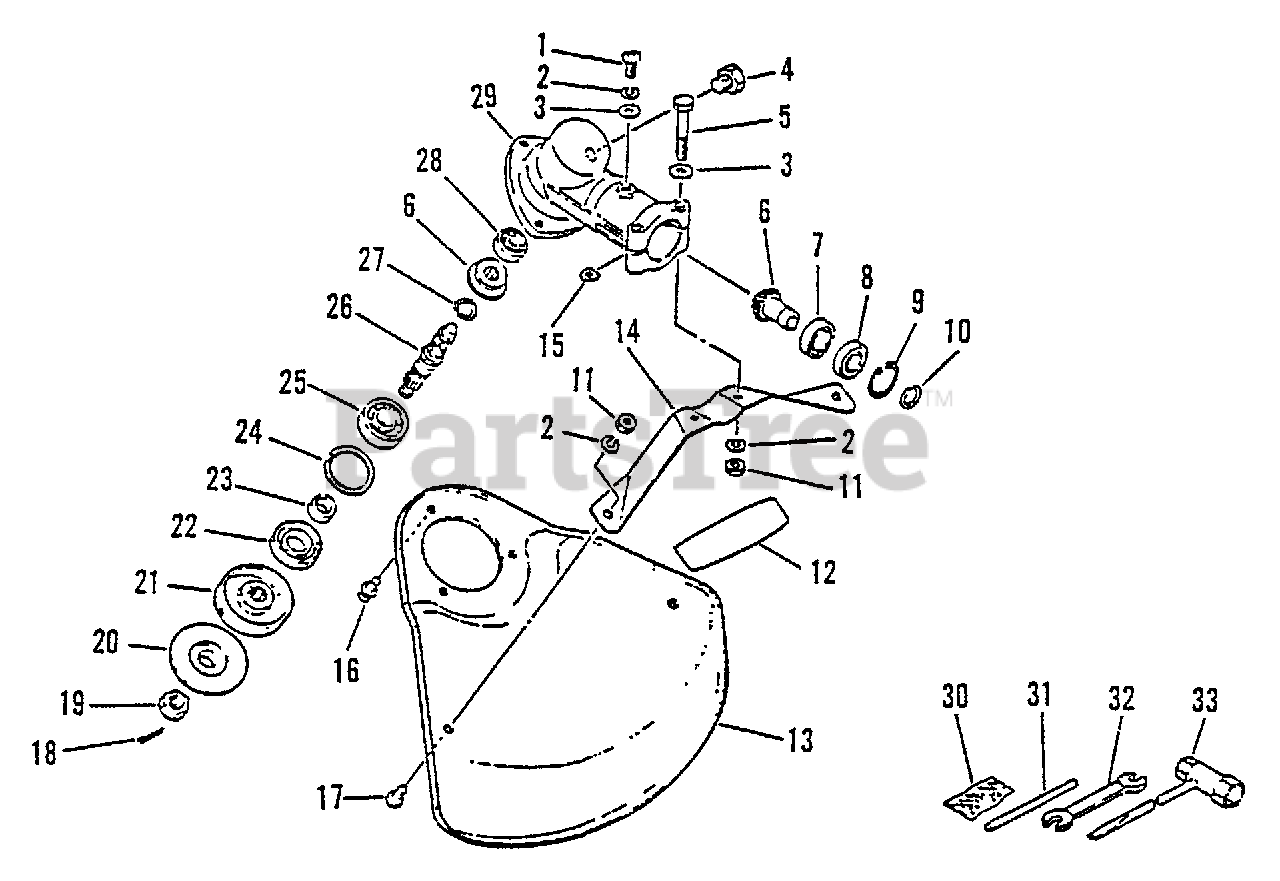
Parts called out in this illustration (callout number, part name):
1	SCREW - 5X10
2	LOCKWASHER - 5
3	WASHER - 5
4	BOLT - 8X8
5	BOLT - 5X35
6	GEAR SET - BEVEL
7	BEARING, BALL - 6900
8	BEARING, BALL - 6900Z
9	RING, RETAINING - 22
10	RING, RETAINING - 12
12	LABEL - CAUTION
13	DEBRIS SHIELD KIT
14	BRACKET, SHIELD
16	SCREW - 5X10
17	SCREW - 5X8
18	PIN, SPLIT - 2X22
19	NUT - 10 -- LEFT HAND
20	ADAPTOR, BLADE - LOWER
21	ADAPTOR, BLADE - UPPER
22	SEAL, OIL
24	RING, RETAINING - 32
25	BEARING, BALL - 6201
26	GEAR - SHAFT
27	RING, RETAINING - 10
28	BEARING, BALL - 609
29	CASE, GEAR
30	PIN, SPLIT - 2X22
31	LOCKING TOOL
32	SPANNER - 8X10mm
33	T-WRENCH - 17X19mm
